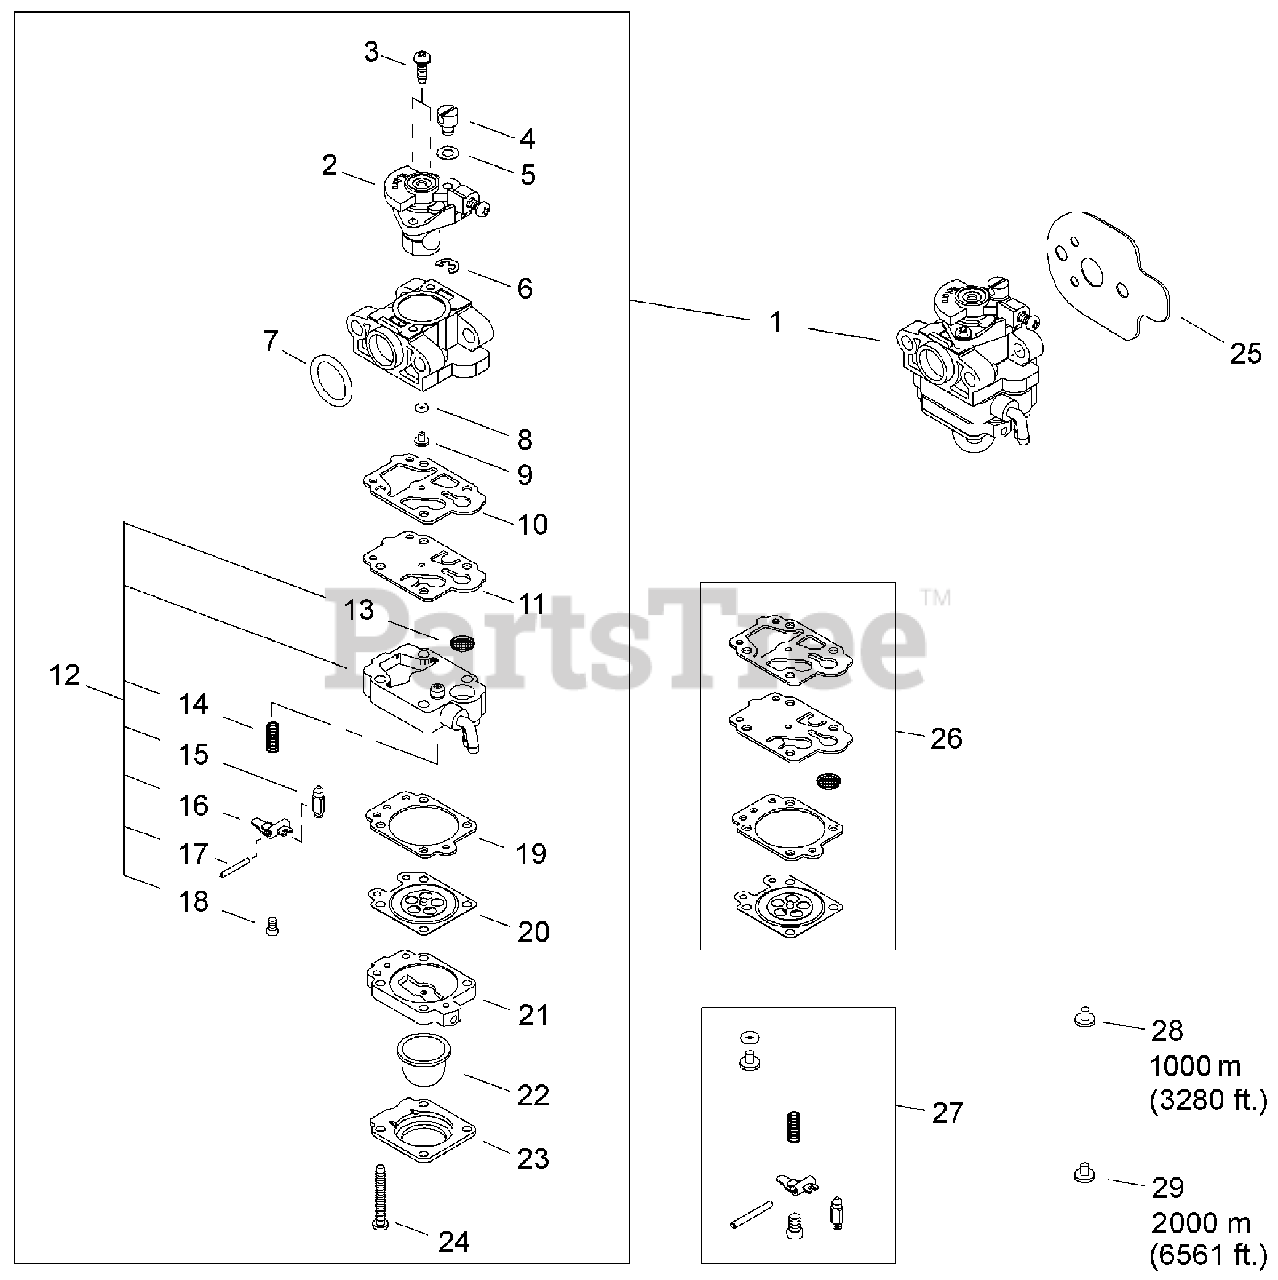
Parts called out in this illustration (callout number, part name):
1	CARBURETOR
2	THROTTLE VALVE ASSY
3	SCREW
4	SWIVEL
5	WASHER
6	RING, RETAINING
7	O-RING - 15
8	O-RING
9	JET, MAIN
10	GASKET, PUMP
11	DIAPHRAGM, PUMP
12	PUMP BODY ASSY
13	STRAINER
14	SPRING, METERING LEVER
15	VALVE, INLET NEEDLE
16	LEVER, METERING
17	PIN, METERING LEVER
18	SCREW, METERING LEVER PIN
19	GASKET, METERING
20	DIAPHRAGM, METERING
21	BASE, PURGE
22	BULB, PURGE
23	RETAINER, PURGE BULB
24	SCREW, PUMP COVER
25	GASKET, INTAKE
26	DIAPHRAGM/GASKET KIT
27	INLET NEEDLE VALVE KIT
28	JET, MAIN - 1000M #40
29	MAIN JET - 2000M #39
